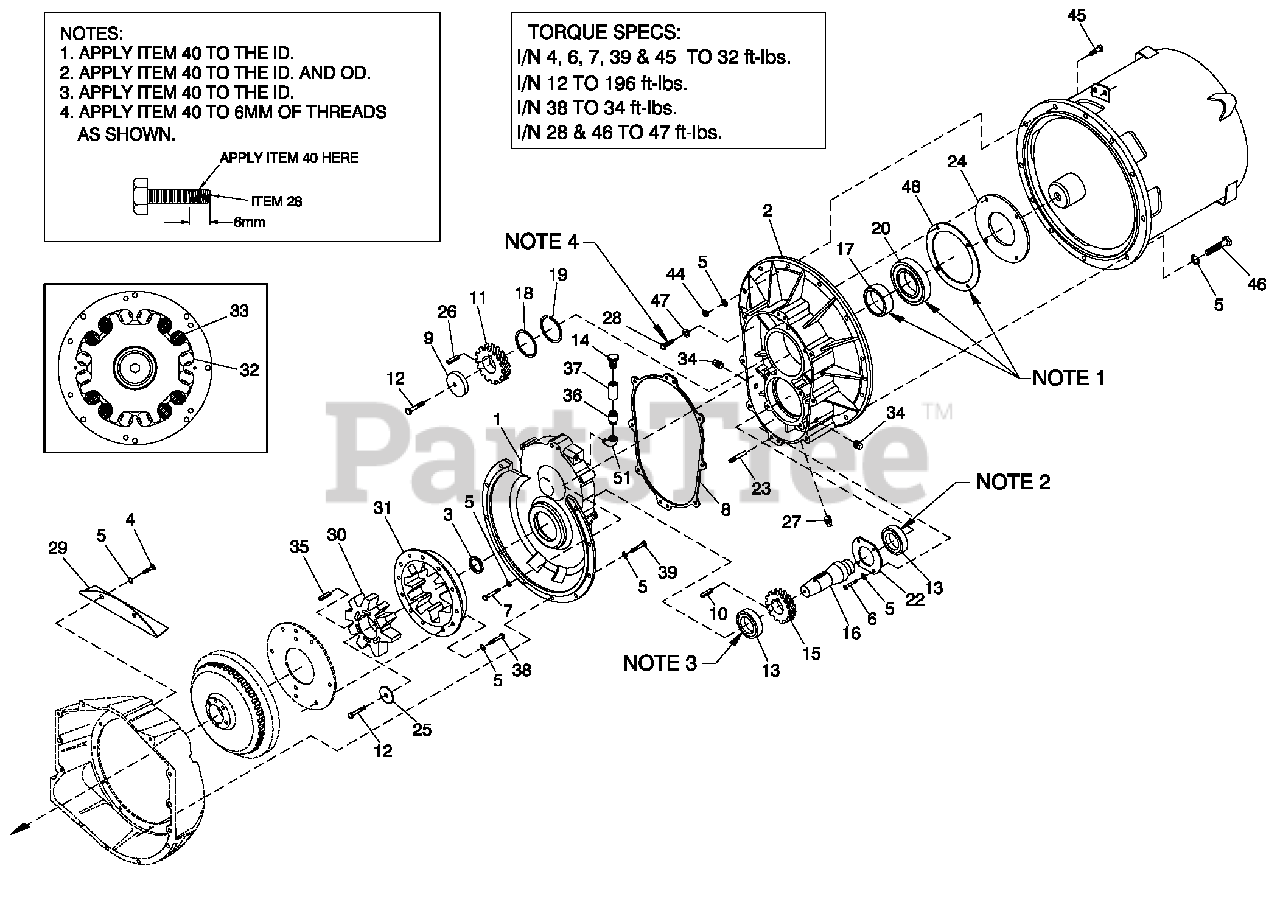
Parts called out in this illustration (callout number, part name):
1	GEAR CASE ENG. MACHINED
2	GEAR CASE ALT. MACHINED
3	SEALOIL
4	S CREW HHC M10l1.5X 20 G8.8
5	WASHER LOCK M10
6	S CREW HHC M10l1.5X 25 G8.8
7	S CREW HHC M10l1.5X 70 G8.8
8	GASKET 390 GEAR BOX
9	S PACER .69 X 2.75 X .37 ST/ZNC
10	KEY 10X16X46
11	GEAR OUTPUT 1.65:1
12	SCREW HHC M16-2.0X 35 G10.9
13	BALLBRG65X 120X23
14	BREATHER
15	GEAR INPUT 1.65:1
16	SHAFT 390 INPUT GEAR
17	COLLAR HARDENED
18	SEALOIL
19	SNAP RING INT 120MM
20	BEARING #6213 SEALED
22	PLATE INTRNLBRG RET
23	PIN DOWEL M8X 24
24	PLATE BEARING THRST
25	SPACER STRESSPROOF
26	KEY 10X16X40
27	PLUG PIPE 3/8"MAGNETIC
28	SCREW HHFC M10-1.5X 25 G10.9
29	COVER GEARBOX GUARD
30	COUPLING INNER DRAWN
31	COUPLING OUTER MACHN
32	DAMPER GB CPLRVIBRA
33	DAMPER GB CPLRVIBRA
34	PLUG STD PIPE 3/8 STEEL SQ HD
35	KEY 10X16X50
36	NIPPLE PIPE3/8NPTX 3-1/2
37	COUPLING FULL 3/8-18
38	SCREW HHC 3/8-16 X1-1/2G8
39	SCREW HHC M10l1 .5X 25 G8.8
40	RETAINING COMPOUND
44	NUTHEXM10-1.5G8 YEL CHR
45	SCREW HHC M10l1 .5X 60 G8.8
46	SCREW HHC M10l1 .5X 40 G10.9
47	WASHERFLATM10SEALING COPPER
48	GASKET SEAL PLATE 390 G B
50	THREADLOCK AND SEALANT
51	ELB OW 90DSTREET3/8
